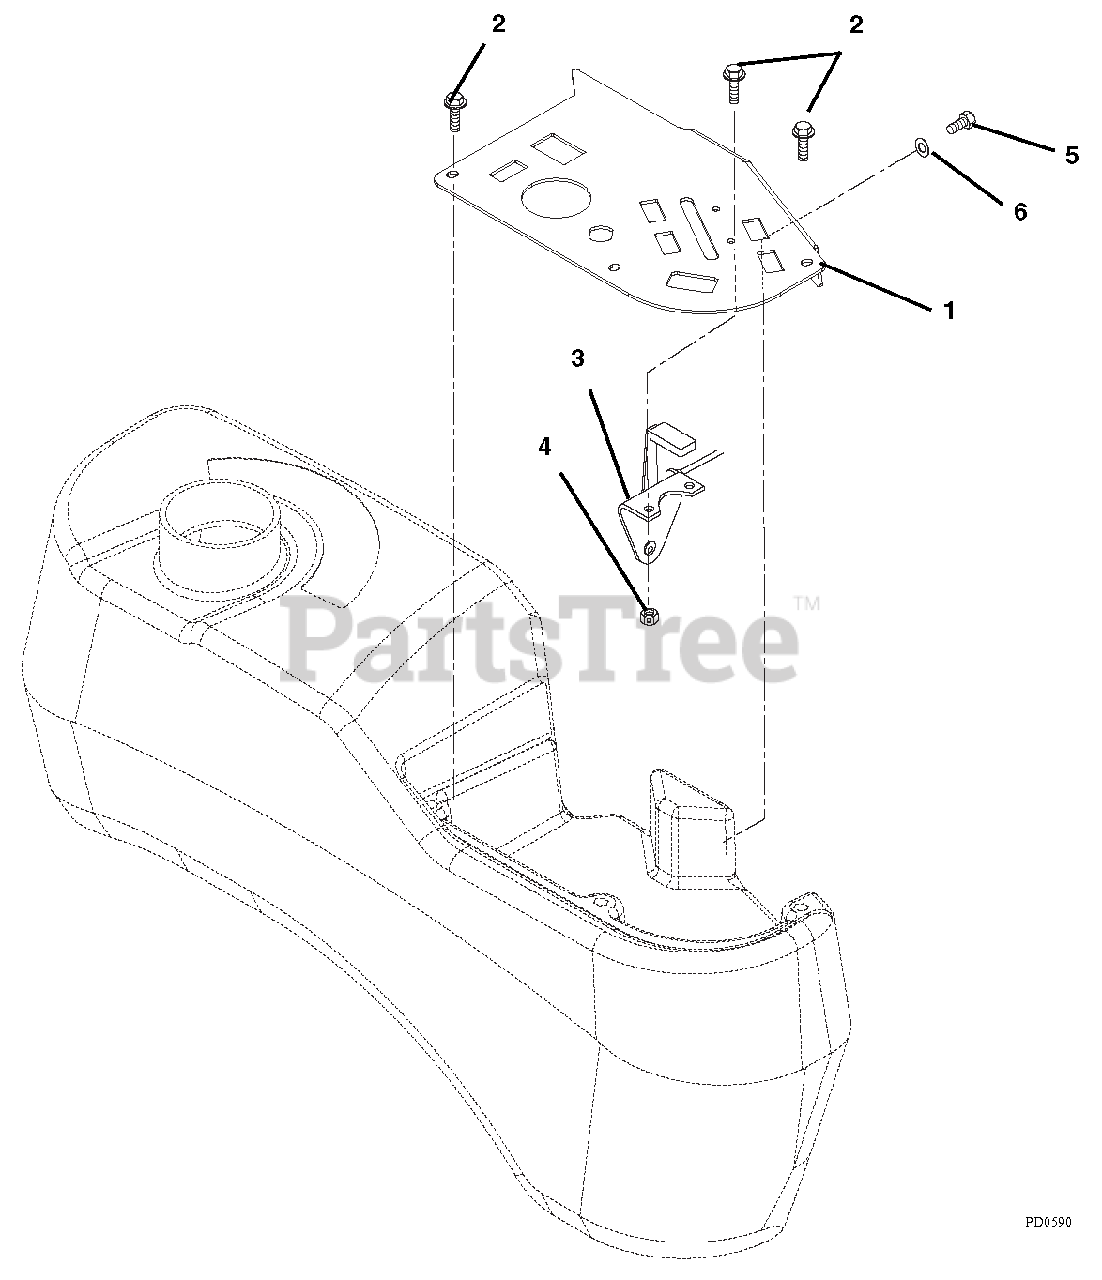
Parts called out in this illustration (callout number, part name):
1	PANEL, CONTROL MZ DIESEL BLACK
2	SCR-MCH 10-24X.50 HWHSTAINLESS
3	CABLE, THROTTLE-DIESEL
4	@NUT-LK-NYL 10-24 W/INSRT YWZC
5	@BLT-HEX .31-18X.75 GR5 YWZC
6	@WSHR-FL-STL.38X.875X.083 YWZC
